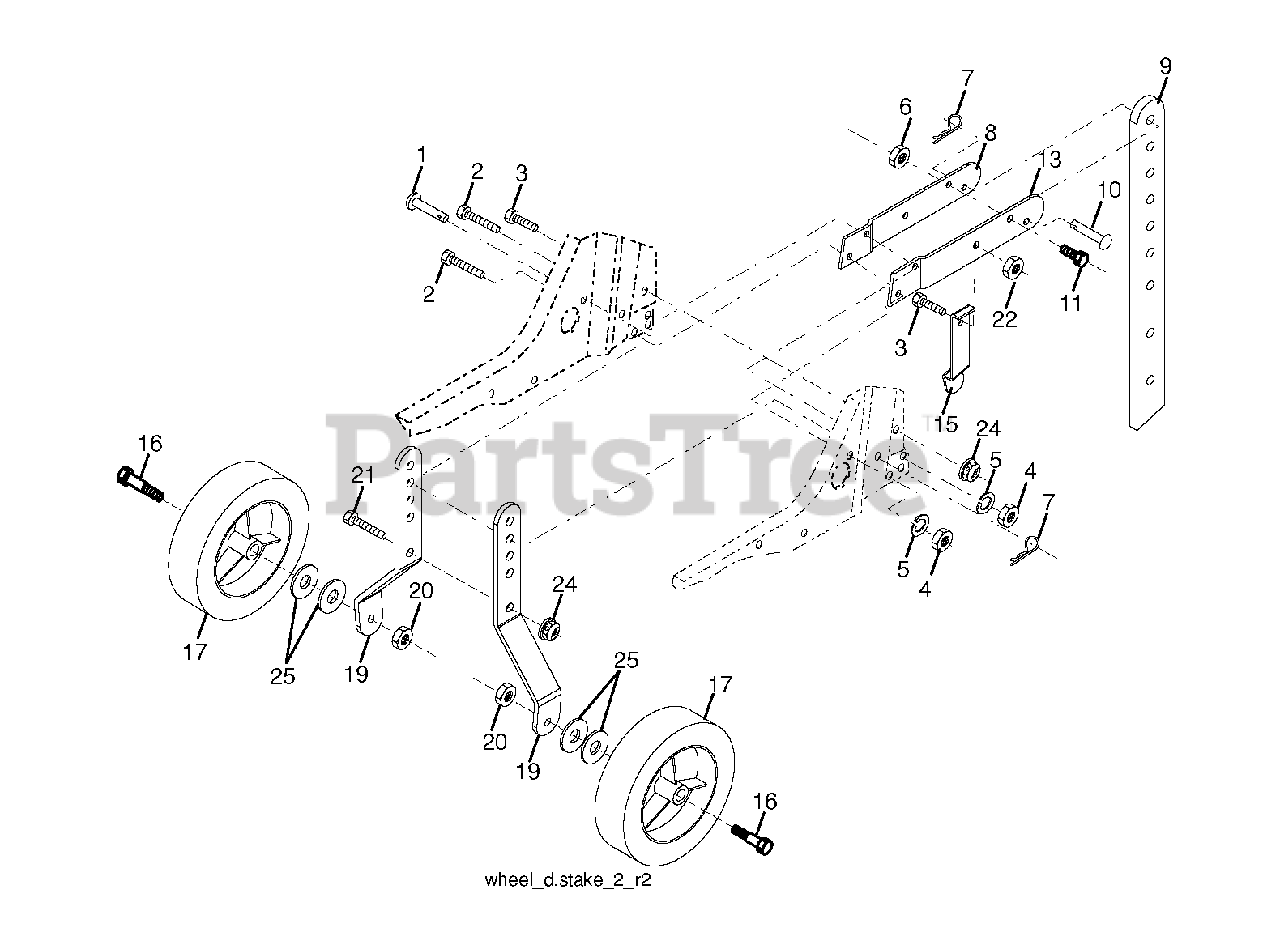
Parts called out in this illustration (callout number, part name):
1	PIN
2	BOLT
3	BOLT
5	LOCKWASHER
6	NUT
7	SPRING TI
8	SUPPORT.STAKE.RH.BLACK
9	RP STAKE.DEPTH.13.25.W/9HOLES
11	BOLT
16	BOLT.SHOULDER
17	WHEEL.8X1.75.STORM.GREY
20	LOCKNUT
21	BOLT RB
22	NUT.71038.31-18.HEX.NYLOCK
24	LOCKNUT-FLANGE 5/16-18
